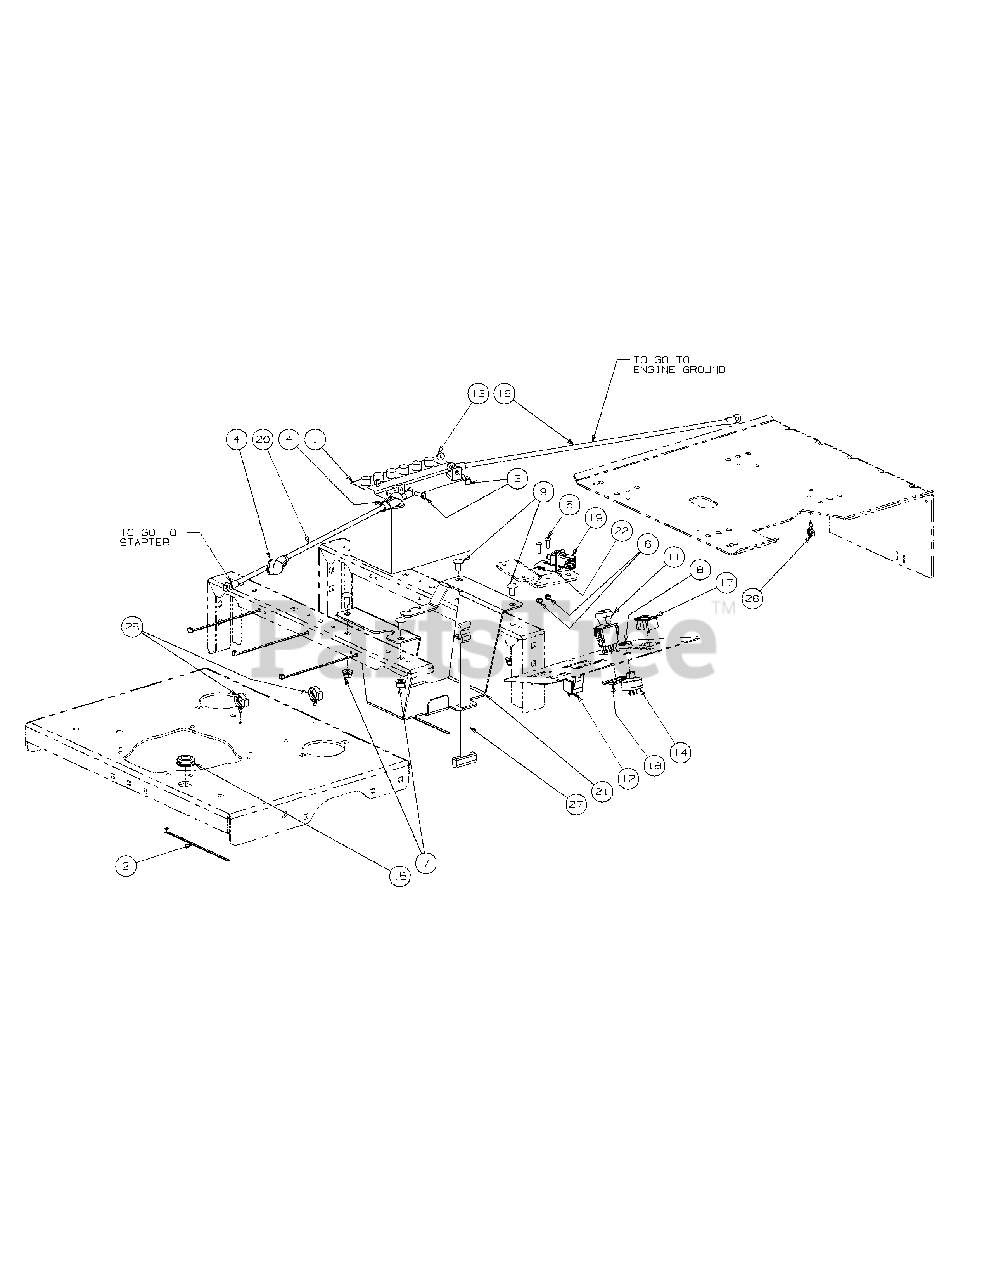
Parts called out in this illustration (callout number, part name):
1	Battery, 12V 225CCA 30 Min
2	Tie, Cable, 3/16 x .05 x 7.4"
3	Screw, Hex, Cap, 1/4-20 x .75
4	Boot, 1" OD Rubber Battery-PST, Red
5	Round Hd. Machine Screw, 10-32 x 3/4
6	Lock Nut, Nylon Insert
7	Flange Lock, Hex Nut, 3/8-16
8	Nut, W/Cap, 5/8-32 Ignition
9	Carriage Bolt, 3/8-16 x .75 Long
10	Hourmeter, Harness
11	Switch, Electric, PTO
12	Relay, 12V 40A
13	Lock Nut, 1/4-20
14	Switch, Ignition, 6 Pin
15	Grommet, .75 ID
16	Cable, Battery Red, 28"
17	Meter, Hour includes:
18	Bracket, PTO Switch Retainer
19	Switch, Safety N.O./N.C.
20	Cable, Battery, Red, 42"
21	Battery Bracket
22	Control/Brake Panel Switch
23	Wire Harness Adaptor
24	Harness Assembly
25	Electrical Conduit Clip, 5/8
26	Electrical Conduit Clip, 3/8
27	Strap, Battery
